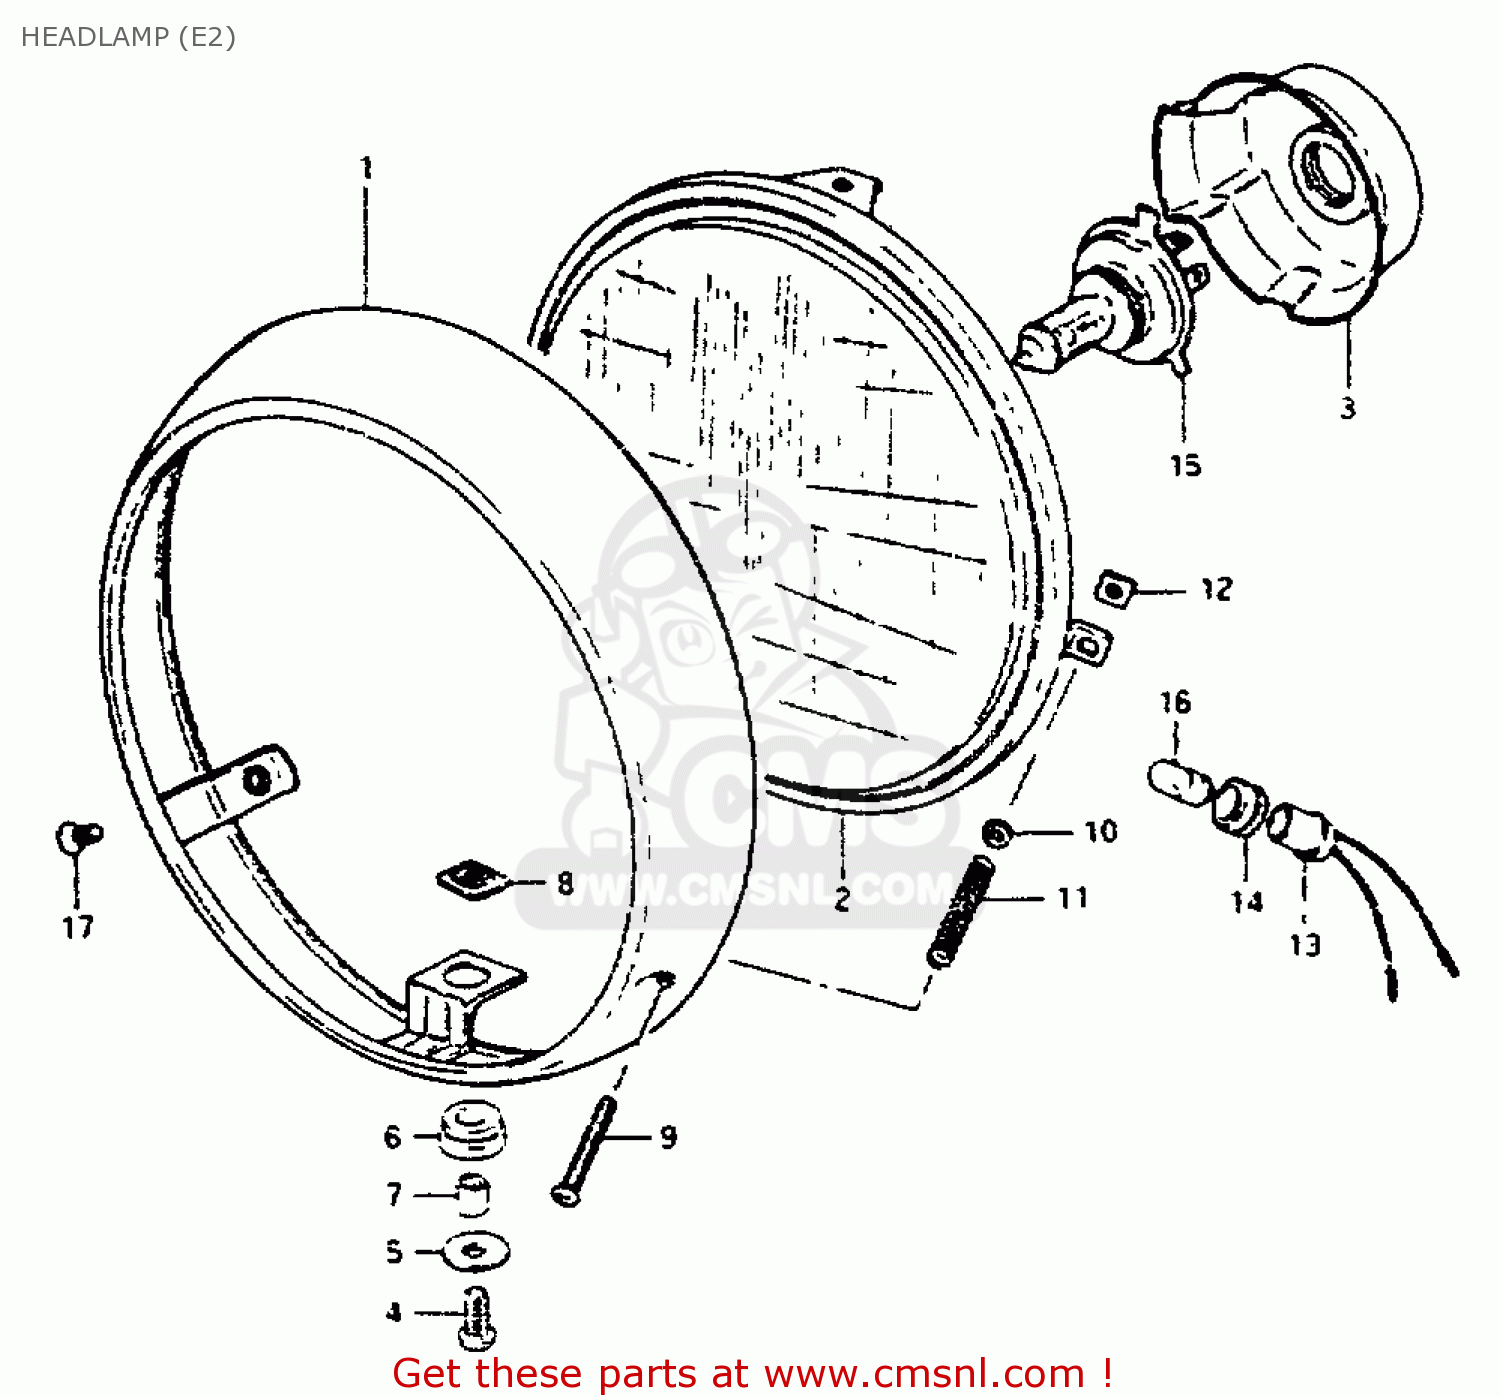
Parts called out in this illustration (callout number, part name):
1	RIM
2	UNIT
3	COVER,SOCKET
4	SCREW
5	WASHER
6	CUSHION
7	SPACER
8	NUT
9	SCREW
10	WASHER
11	SPRING,HEADLAMP ADJUST
12	NUT,HEADLAMP ADJUSTER
13	SOCKET
14	JOINT,RUBBER
15	BULB(12V60/55W,H4)
16	BULB
17	SCREW
